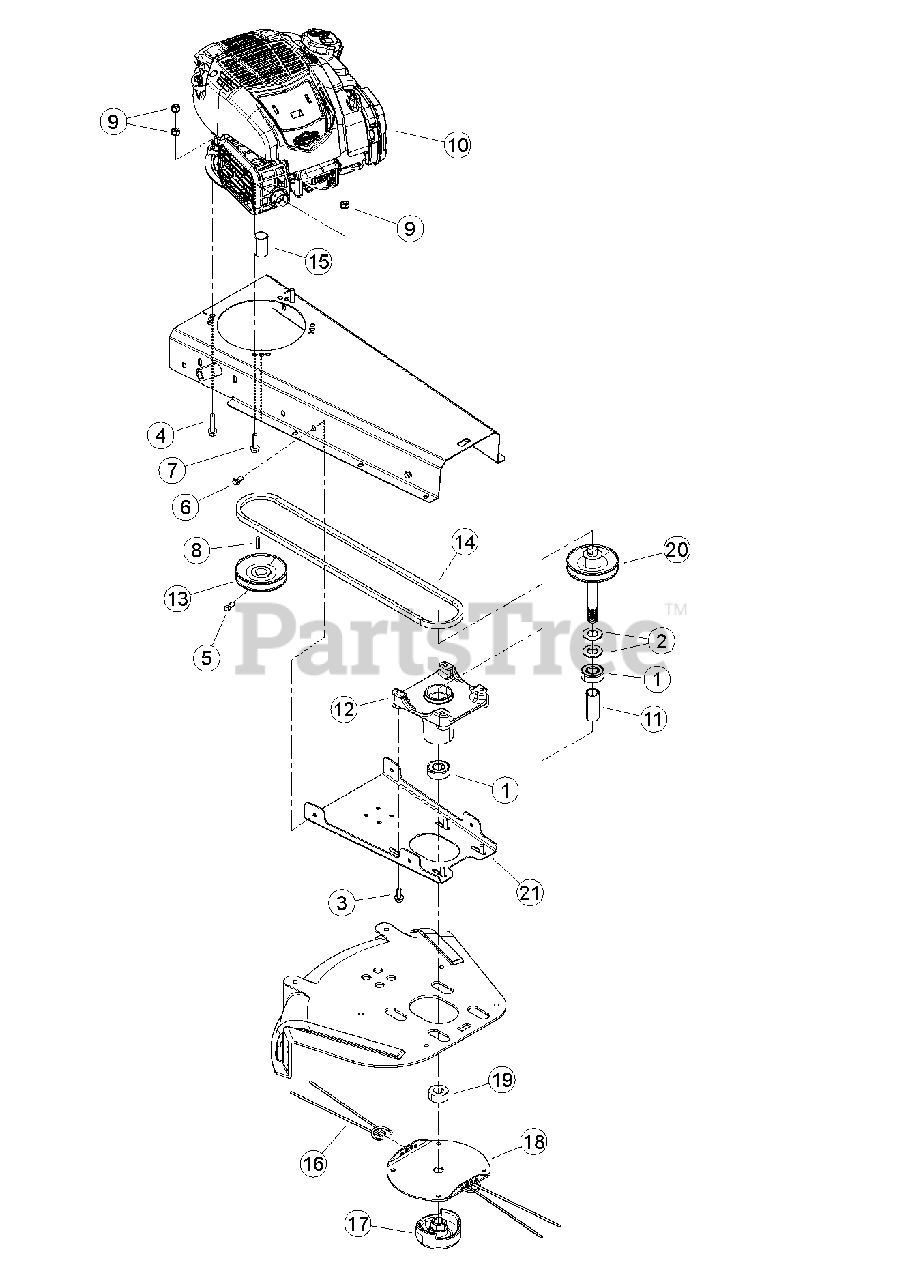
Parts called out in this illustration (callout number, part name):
1	BEARING, 3/4 BALL
2	WASHER, 3/4" SAE FLAT ZP
3	BOLT, 5/16 X 3/4 FLANGE NC
4	BOLT, 5/16 X 1-1/2 FLANGE NC
5	SCREW, 5/16-18 X 5/8 SQ HD SET
6	SCREW, 11/32-12 X 7/8 FLANGE T-AB
7	BOLT, 5/16 X 1-1/4 FLANGE NC
8	KEY, 3/16" X 1.00" LG SQUARE
9	NUT, 5/16-18 NYLOCK FLANGE
10	ENGINE, BRIGGS 163CC VERTICAL (FOR SERVICE SEE ENGINE OWNER'S MANUAL OR NEAREST BRIGGS & STRATTON INDUSTRIAL ENGINE DEALER)
11	SPACER, TRIMMER SPINDLE
12	CASTING, TRIMMER SPINDLE HUB
13	PULLEY, ENGINE 4.0 X .875 B GROOVE
14	BELT, AX48
15	SPACER, 1-1/16 OD X 14 GA X 1.630
16	STRING, 20" X .155 DIA. CROSS-FIRE
17	MOWBALL, CAST TRIMMER PAINTED
18	DISK, TRIMMER HEAD
19	SPACER, TRIMMER HEAD
20	WELDMENT, SPINDLE HW MODELS
21	PLATE, SPINDLE CASTING MOUNT
